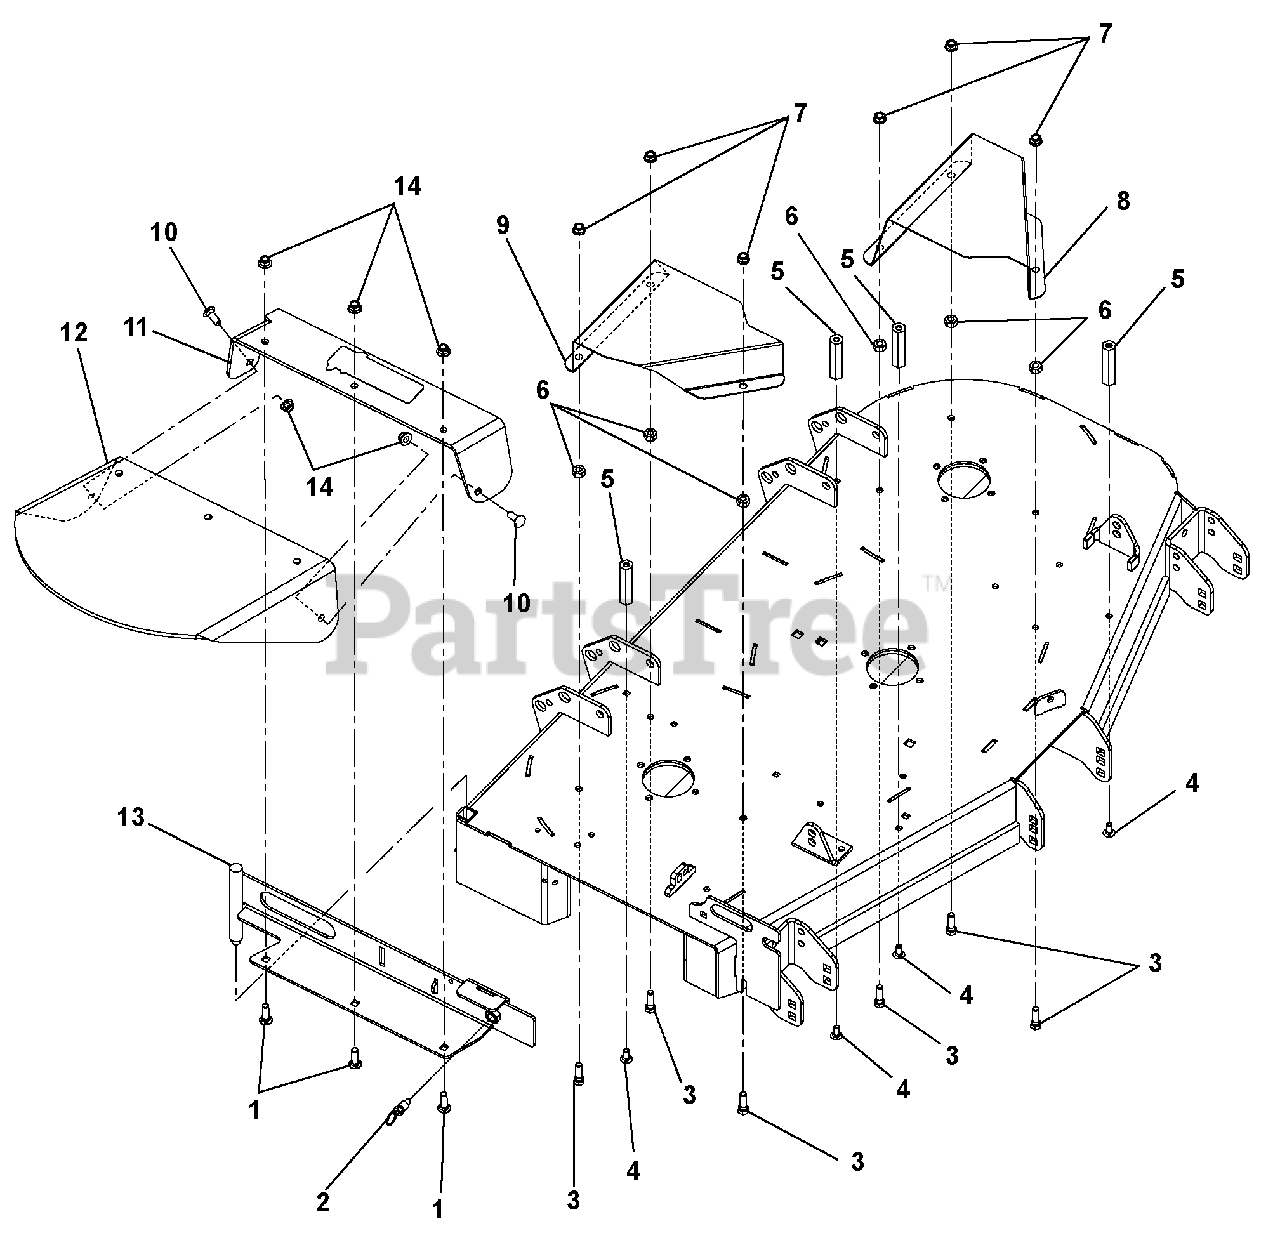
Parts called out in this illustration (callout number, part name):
1	Bolt, Round Head Square Neck .38-16 x 1.25 Grade 5
2	Pull Pin
3	Bolt, Hex .38-16 x 1.25 Grade 5
4	Bolt, Round Head Square Neck .31-18 x .75
5	Nut, Coupling .31-18 x 3.00
6	Nut, Heavy Hex .38-16
7	Nut, Flange .375-16
8	Guard, 44-52 Left Hand Spindle Sheave (060, 061)
9	Guard, 44-52 Right Hand Spindle Sheave (060, 061)
10	Bolt, Round Head Square Neck .38-16 x 1.00 Grade 5
11	Rubber Discharge Chute Support
12	Chute, Rubber Discharge
13	Weldment, 48" Discharge Chute Support (060)
14	Nut, .38-16 Nyloc Flange
